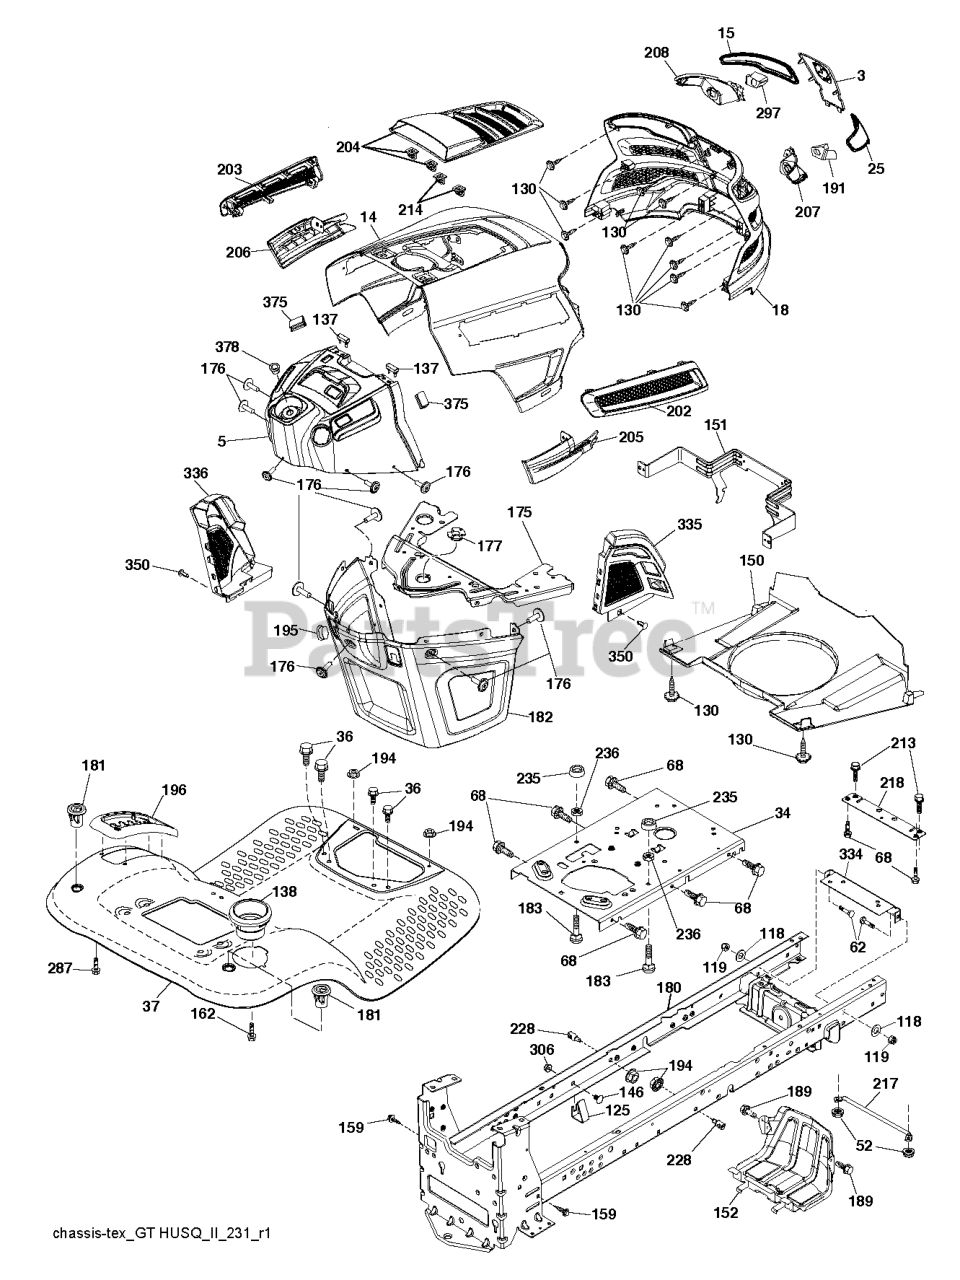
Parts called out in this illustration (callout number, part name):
3	APPLIQUE.SUBASM.GT.HUSQ.II
5	DASHBOARD.UPPER.ASM.GT2.X498
14	HOOD.ASM.HUSQVARNA.GT.TEX.ORAN
15	LENS.HEADLIGHT.LH.GTII.2011
18	GRILLE SUBASM.GT.II.LOW.HDLGHT
25	LENS.HEADLIGHT.RH.GTII.2011
34	PLATE.ENGINE.WELDED.CHASSIS
36	SCREW 5/16"
37	FENDER.TLT.FS.W/CUPHLD.ORANGE
118	WASHER PLAIN WASHER 3/8 X 0.08
125	CLIP.FUEL.LINE
137	BUMPER DASH
138	HOLDER.CUP.LT.GREY
146	BOLT.RDHD.SHT.SQNK.3/8-16X5/8
150	AIR.DUCT.GTV2(2.54"RING HEIGHT
151	BRACKET.PIVOT.HOOD.GT.HUSQ.II
152	SHIELD.BROWNING.PNT.GT.V2
159	SCREW, 3/8-16X3/4
175	PLATE.PNT.CROSSMEMBER.HUSQ/PRE
176	SCREW.#10-24X5/8.RN.QU
177	BUSHING STEERING
180	CHASS.WLDMNT.TL.12GA/2P.48/54
181	BUSHING.MNT.FEND.CRGO.TEX.49
182	DASH LOWER.HUSQ.PRED NO CRUISE
189	SCREW
191	INSERT.REFLECTIVE.RH.HUSQ.GTII
195	PLUG.HOLE.DASH.LOWER.12V.BLK
196	DECKLFT.CONSOL FULL ASSM GREY
202	VENT.SIDE.RH.GT.HUSQ.II.
203	VENT.SIDE.LH.GT.HUSQ.II.498
204	VENT.TOP.ASM.HUSQ.GT2
205	SIDE.TRIM.RH.GT.HUSQ.II
206	SIDE.TRIM.LH.GT.HUSQ.II.GRAY
207	HEADLIGHT.CUP.BEZEL.HUS.GT2.RH
208	HEADLIGHT.CUP.BEZEL.HUS.GT2.LH
213	SCREW HEXAGON HEAD SCREW 5/16-
214	CLIP.RETAINER.TINNER.
217	ROD.PIVOT.HOOD
218	X-PIECE.HOOD.STOP.NON/
228	STUD.W/"D"ANTI-ROTATION
236	NUT.CENTERLOCK.5/16-
287	SCREW 1/4X20
297	INSERT.REFLECTIVE.LH.HUSQ.GTII
306	NUT LOCK FLG 3/8-16 UNC
334	BRACKET.ENGINE
335	COVER.LOWER.DASH.RH.BLACK
336	COVER-LH.LOWER.DASH.GT2.BLACK
350	CLIP.X-MAS.TREE
375	BUMPER CLIP-ON. DASH 1"
378	BUSHING FLANGE; PLASTIC
